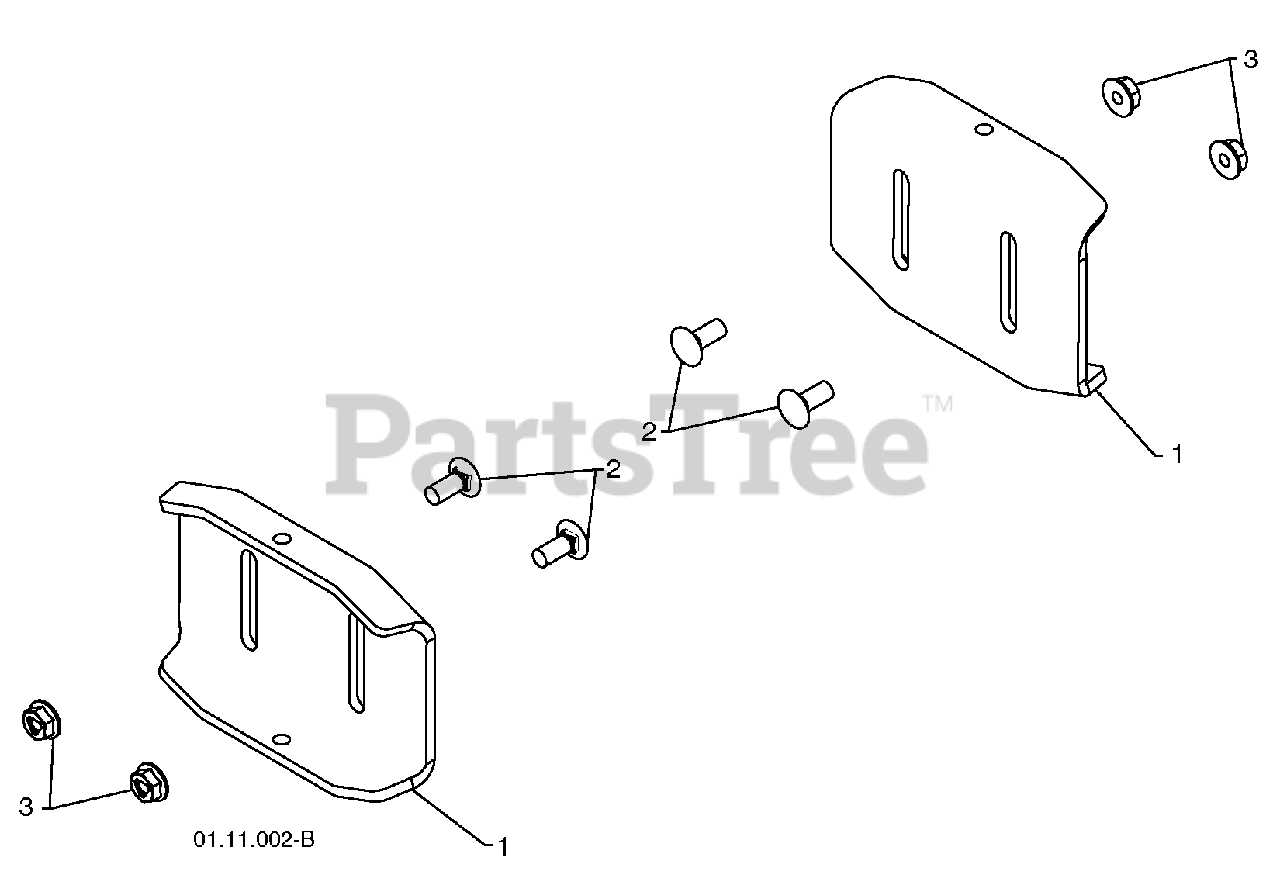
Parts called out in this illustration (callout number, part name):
1	Skid Plate
2	Carriage Bolt 5/16-18 X .750
3	Nut 5/16-18
